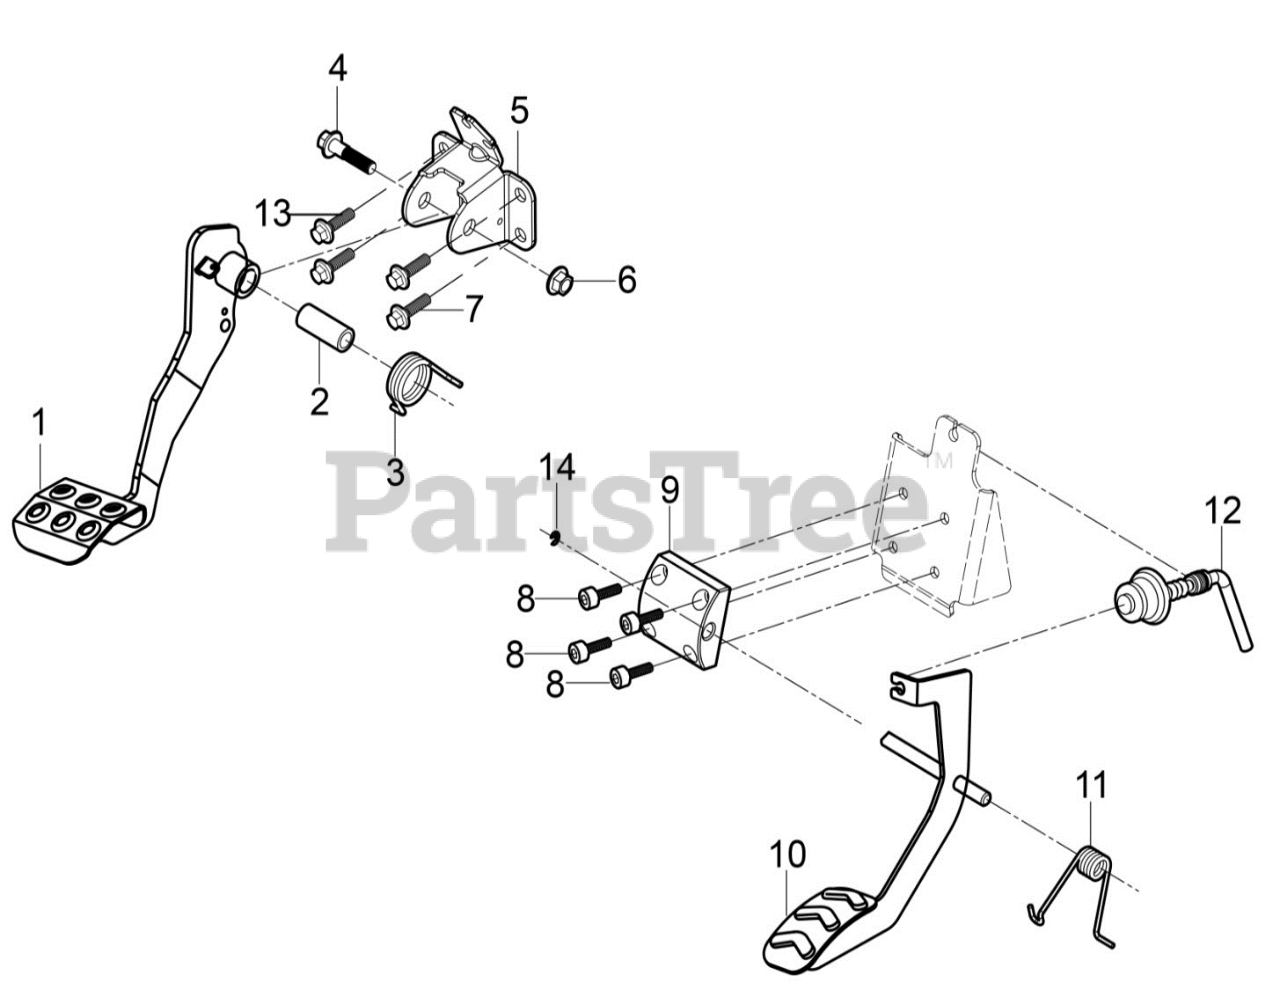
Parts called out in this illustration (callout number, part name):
1	BRAKE PEDAL
2	SPACER 10.2X15X35.5
3	TORSION SPRING J
4	HEX FLANGE BOLT M10X1.25X60
5	PLATED STRAP BRAKE PEDAL
6	LOCK NUT M10X1.25
7	HEXAGON FLANGE BOLT M8X20
8	SOCKET HEX HEAD SCREW M6X20
9	THROTTLE PEDAL BRACKET
10	ACCELERATOR PEDAL
11	TORSION SPRING
12	THROTTLE CABLE
13	FLANGE BOLT M8X25
